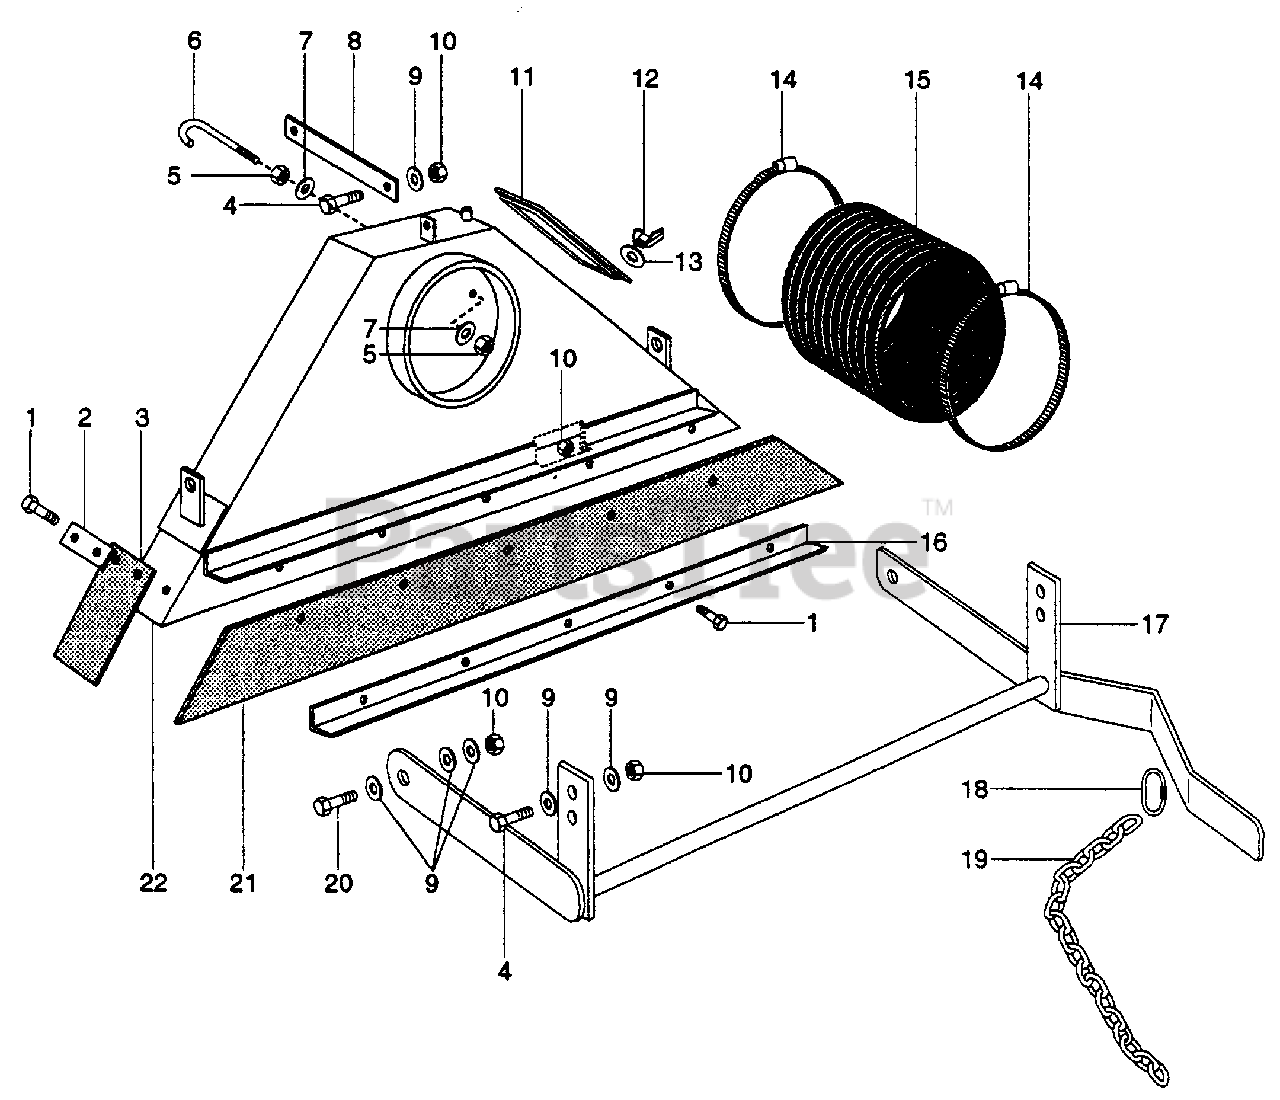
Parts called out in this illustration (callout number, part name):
1	BLT-HEX .38-16 X 1.00
2	END BOLTING STRIP
3	FLEX SKIRT ENDCAP
4	BLT-HEX .38-16 X 1.25 PL GR 2
5	NUT .50-13 X 5.00 PL GR 2
6	J-BOLT
7	WSHR-FL-STL .531 X 1.062 X .095
8	SCOOP STABILIZER BRACE
9	WSHR-FL-STL .406 X .812 X .065 PL
10	NUT-LK TOP .375-16 GR C PL
11	SCOOP SIDE COVER
12	NUT-WING .375-16 PL
13	WSHR-FL-STL .438 X 1.0 X .083 PL
14	CLAMP
15	FLEX HOSE
16	RETAINER STRIP
17	SCOOP LIFT WELDMENT
18	1/4 QUICK LINK
19	10 LINK 1/4 CHAIN
20	BLT-HEX .38-16 X 1.50 PL GR 5
21	FLEX SKIRT FRONT
21	FLEX SKIRT REAR
22	SCOOP WELDMENT
